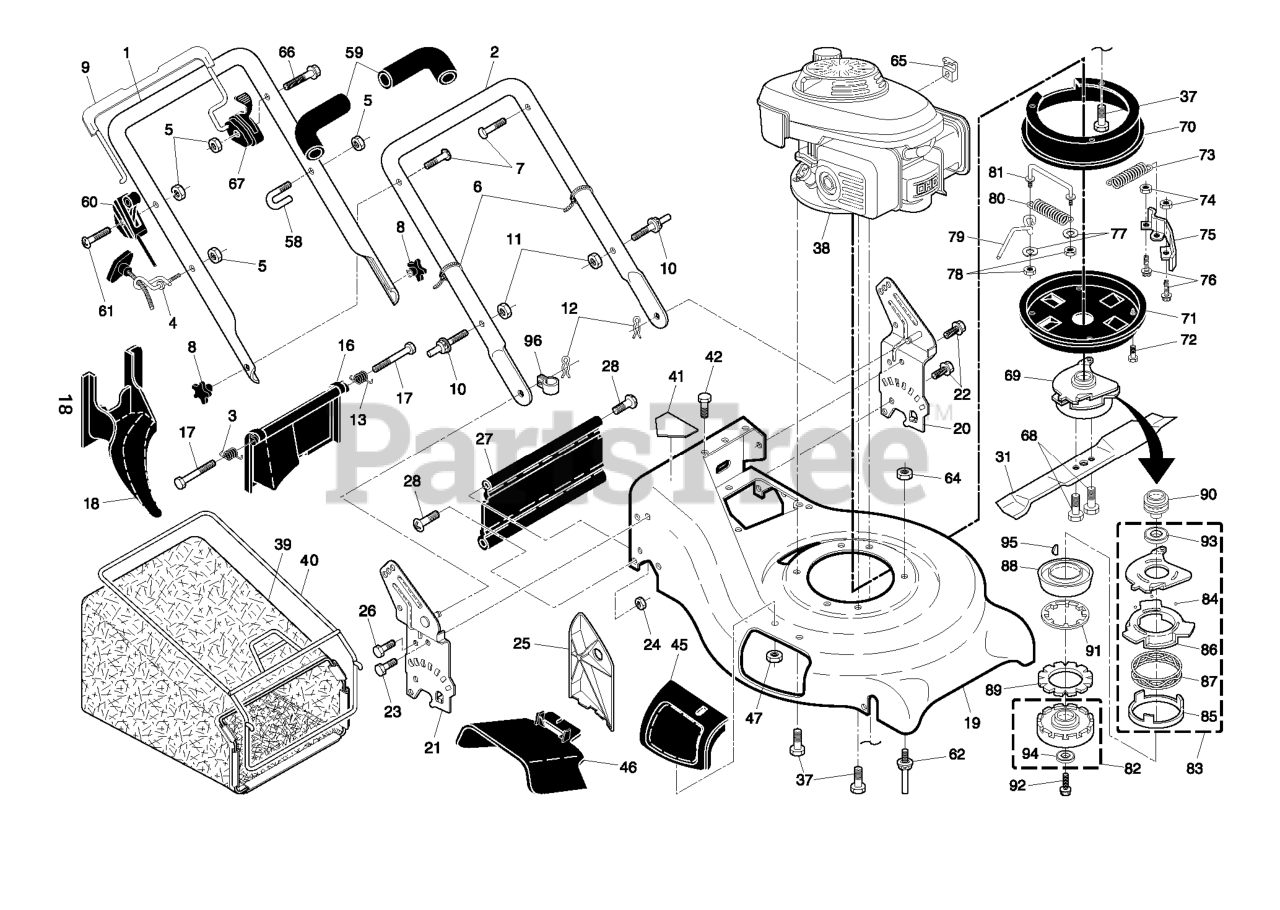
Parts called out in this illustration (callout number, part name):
1	HANDLE.UP.ASM.DSTRT/FLT
2	HANDLE.LOWER.21.GREY
3	SPRING.RH.REAR.DOOR.21.RWGD
4	RB GUIDE.ROPE.STD.BLK.ZIN WSL
5	NUT
6	TIE GUIDE
7	BOLT, HANDLE 5/16-18X1.75
8	KNOB.HANDLE.STAR.HUSQ.GRAY
9	CONTROL BAR, AUTO-WALK
11	NUT.LOCK.5/16-18
12	HAIRPIN COTTER
13	SPRING.LH.REAR.DOOR.21.RWGD
16	REAR DOOR ASSEMBLY
18	PLUG.MULCHER.RGD.21.
19	HOUSING.21.RWD.MC.MS.EZ/ORANGE
20	BRKT.ASM.HNDL.21.RWGD.LT
21	BRKT.ASM.HNDL
22	SELF-TAPPING SCREW 5/16-18X3/4
23	BOLT, HEX HEAD 5/16-18
24	NUT.71038.31-18.HEX.NYLOCK
25	CLIPPING DEFLECTOR
27	SKIRT.REAR.21.RWGD.BLACK(2 2M)
28	HINGE SCREW
31	BLADE.21".BBC
37	BOLT 3/8-16X1-1/8
39	GRASSBAG
40	FRAME.GBAG.21.RWGD.SC
41	DANGER DECAL
45	MULCHER DOOR ASM.
46	DEFLECTOR, DISCHARGE
59	GRIP.HANDLE.FOAM.WIDE.(1 SIDE)
60	CONTROL.THROTTLE.HONDA.BBC
62	STUC.GUIDE.BELT.RWGD
64	NUT.HEX.3/8-16
65	BRACKET.THROTTLE
67	CONTROL.BBC.HV.GRY/ORG
68	BOLT.BLADE
70	COVER.BELT.BBC.AW.TOP
71	COVER.BELT
72	TAPPING SCREW
73	SPRING.BBC
74	NUT T
75	BRAKE, CLUTCH
76	BOLT
79	BELT KEEPER
80	SPRING.LINK.BBC
81	LINK.TORQUE.BBC
82	HOLDER.ASM.BLADE.HONDA.
83	BALL.CONTROL.PLATE.ASSY.BBC.MO
84	BALL.STEEL
85	PLATE.SPRING.HOOK
86	PLATE.BRAKE
87	SPRING BALL PLATE
88	DISC.DRIVE
89	DISK.DRIVEN
90	PULLEY.DRIVE.HONDA.
91	SPRING.CLUTCH.HONDA.
92	BOLT.FLANGE
93	BEARING.RADIAL BALL#6006
94	BEARING RAD. BALL#6204
95	KEY.WOODRUFF.16X15.HONDA
96	CLIP.CABLE.BLK
